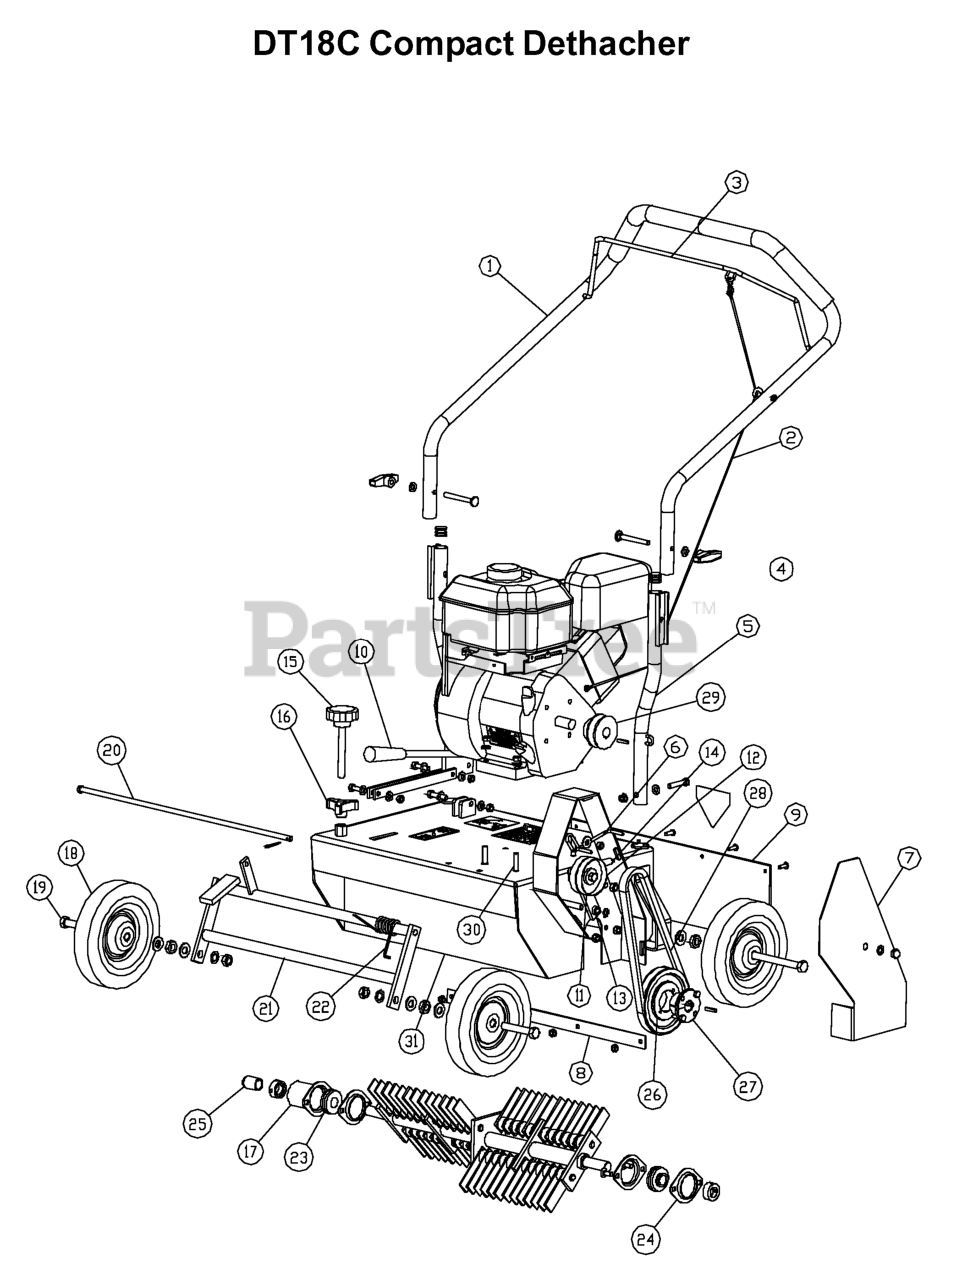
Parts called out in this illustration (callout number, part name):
1	HANDLE ASSEMBLY
2	CLUTCH CABLE ASSEMBLY
4	KNOB
5	LOWER HANDLE ASSY
6	BELT KEEPER KIT
7	BELT GUARD KIT
8	DEFLECTOR KIT
9	DEFLECTOR, NEOPRENE
10	DEPTH LEVER ASSY
11	IDLER ASSY KIT
12	PULLEY
13	MTG ARM, IDLER PULLEY
14	SPRING
15	DEPTH ADJUSTMENT KNOB
16	3-PRONGED LOCK DEPTH
17	ROTOR GUARD
18	WHEEL
19	BOLT KIT
20	LIFT ARM ROD KIT
21	LIFT ARM ASSEMBLY
22	TORSION SPRING
23	BEARING
24	STAMPING KIT
25	ROTOR CAP
26	V-PULLEY
27	BUSHING KIT
28	V-BELT
29	V-PULLEY
30	ENGINE BOLT KIT
